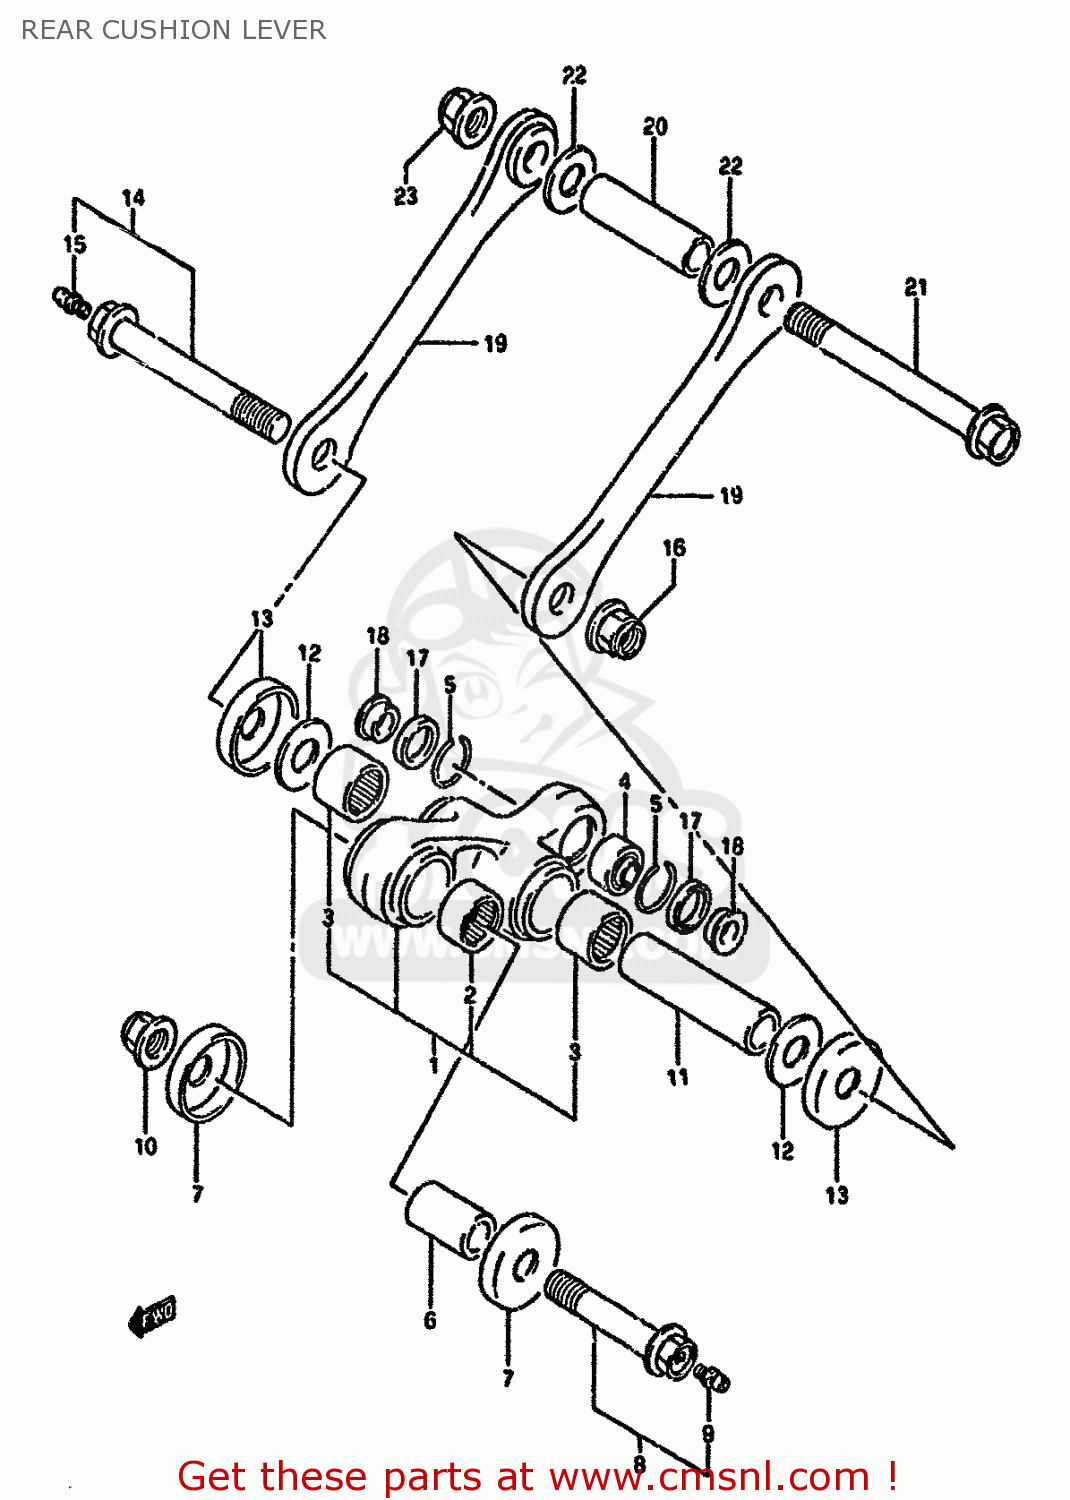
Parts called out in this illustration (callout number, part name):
1	LEVER SET,RR CUSHION
2	BEARING(20X27X32)
3	BEARING(20X27X23.5)
4	BEARING,REAR SHOCK ABSORBER
5	RING,STOPPER
6	SPACER,RR CUSHION LEVER FR
7	SEAL,REAR CUSHION LEVER
8	BOLT,RR CUSHION LEVER FR
9	GREASE NIPPLE
10	NUT 12MM
11	SPACER,RR CUSHION LEVER CTR
12	WASHER
13	SEAL,RR CUSHION LEVER
14	BOLT,RR CUSHION LEVER CTR
15	GREASE NIPPLE
16	NUT
17	SEAL,OIL(17X24X3)
18	COLLAR
19	ROD,RR CUSHION
20	SPACER,RR CUSHION ROD
21	BOLT,RR CUSHION ROD
22	WASHER
23	NUT
